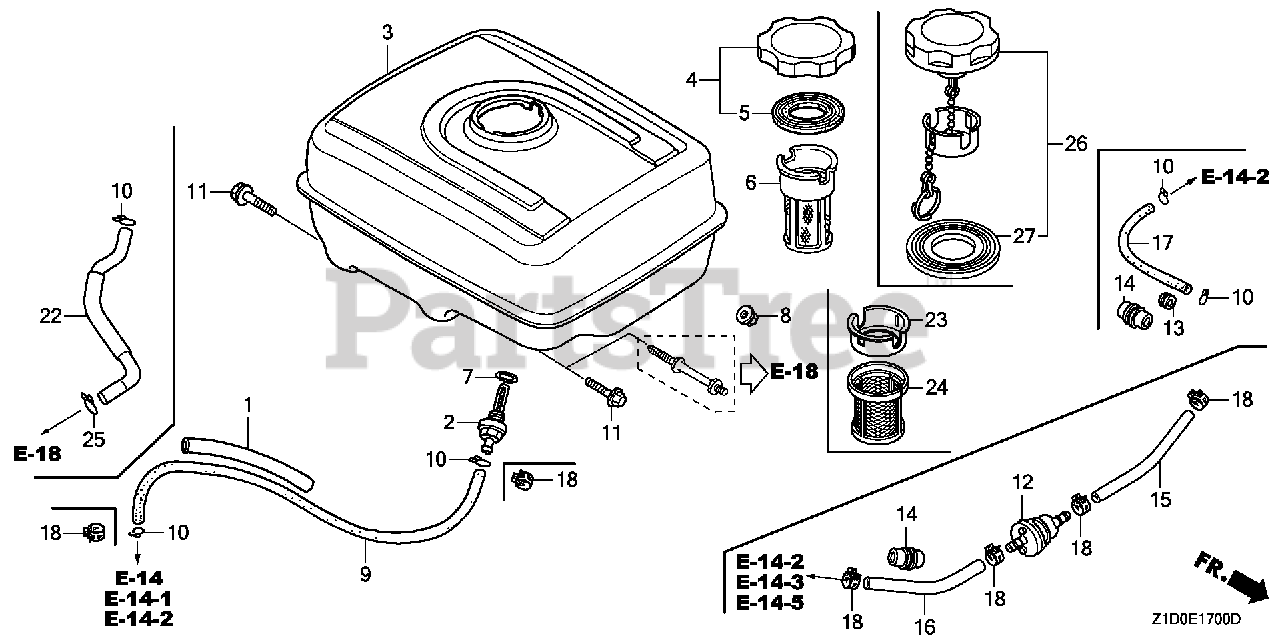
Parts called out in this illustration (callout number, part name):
1	RUBBER, SUPPORTER (107MM)
2	JOINT, FUEL TANK
3	TANK, FUEL *NH1* (BLACK)
3	TANK, FUEL *NH31* (MCKINLEY WHITE)
7	O-RING (13.5X1.5) (ARAI)
7	O-RING (14MM) (NOK)
8	NUT, FLANGE (8MM)
9	TUBE, FUEL (4.5X210) (FKM)
11	BOLT, FLANGE (8X25)
18	CLAMP, TUBE (D8)
26	CAP, FUEL FILLER
27	GASKET, FUEL FILLER CAP (39X62X3) (RADICON)
